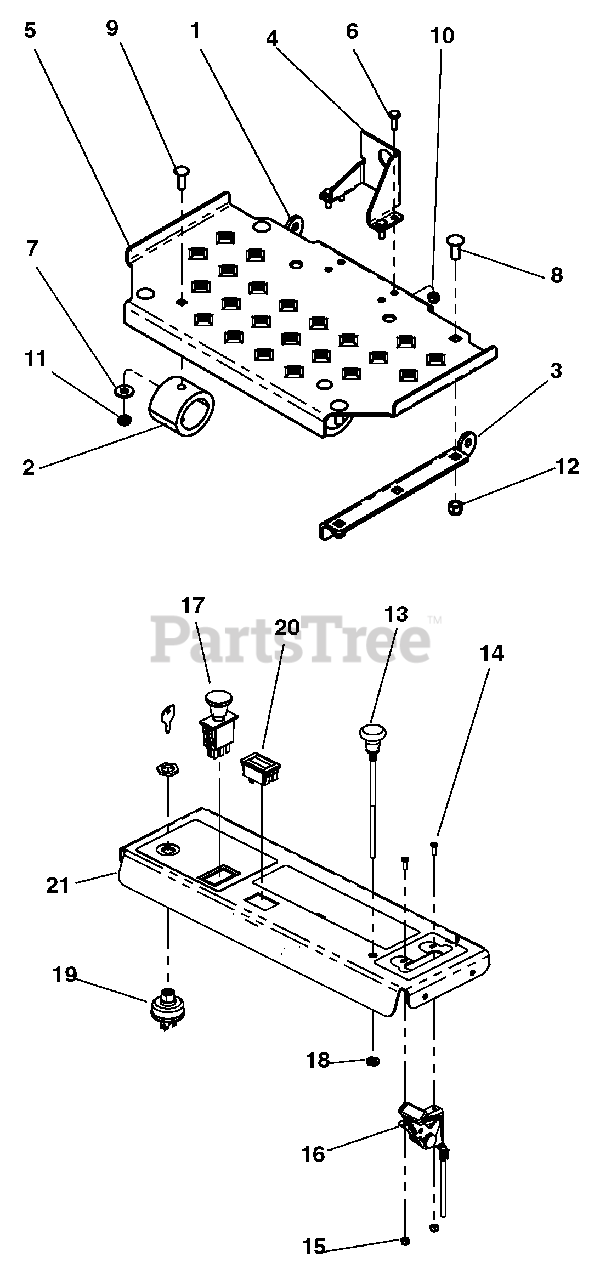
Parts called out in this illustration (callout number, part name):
1	Plate, Platform Tab LH
2	Bumper, Miner GBR-6
3	Plate, Platform Tab Left Hand
4	Anchor, Operator Presence Control
5	Platform
6	Bolt, Hex .25-20 x .75 Grade 5
7	Washer, Flat-Steel .38 x .875 x .083
8	Bolt, .375-16 x 1.00 Round Head Square Neck G 5
9	Bolt, .312-18 x 1.00 Round Head Square Neck Grade 5
10	Nut, Locking-Nylon .25-20
11	Nut, Locking-Nylon .312-18
12	Nut, Locking-Nylon .38-16
13	Cable, Choke
14	Screw, 8-32 x .50 Pan PHL Y
15	Nut, 8-32 Elastic Stop
16	Cable, Throttle
17	Switch, PTO Engagement
18	Nut, Hex .38-16
19	Switch, Key - 3 Position
20	Meter, Hour Digital
21	Top, Console w/Decals
